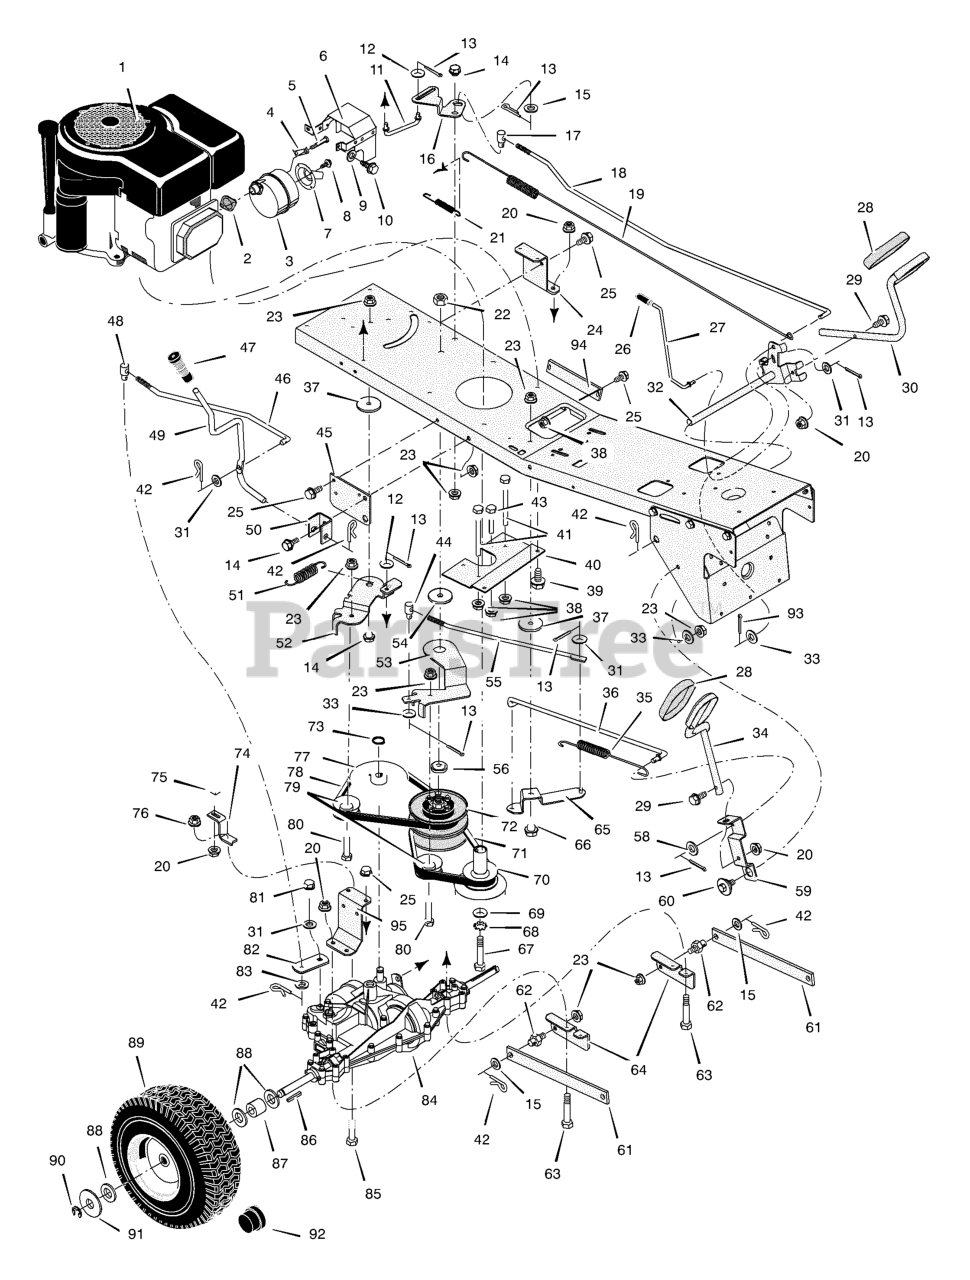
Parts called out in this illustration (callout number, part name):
1	Engine
2	GASKET, Exhaust
3	Muffler
4	Lock, Muffler Screw
5	Bolt, Hex
6	Shield, Heat
7	Tube, Exhaust
9	Washer, Lock
10	Screw
11	Rod, Link
13	Pin, Cotter
14	Bolt, Shoulder
15	Washer
16	Link, Clutch
17	NUT, Adjusting, 1/2-13
18	Rod, Clutch Variator
19	Spring, Brake
20	Nut
21	Spring, Brake Return
23	Nut
24	Bracket, Transaxle -Left
27	Rod, Parking Brake
28	Pad, Pedal
29	Bolt, Hex
30	Rod, Clutch/Brake
32	Rod, Clutch/Brake Pivot
33	Washer
34	Pedal, Variator
35	Spring, Return
36	Rod, Variator Connect
38	Nut
39	Screw
40	Plate, Belt Guide
41	Guide, Belt -Long
42	Pin, Hair
43	Guide, Belt -Short
44	Nut, Adjusting
45	Bracket, Lift Pivot
46	Rod, Shift Link
47	Grip
48	Nut, Adjusting
49	Lever, Shift
50	Bracket, Pivot
51	Spring - Variator Drive
52	Arm, Idler
53	Arm, Clutch Ider
55	Link, Drive
58	Washer
59	Arm, Pedal
60	Bolt, Shoulder
62	Pin, Threaded
63	Bolt, Hex
64	Bracket, Rear Hanger
65	Link Assembly, Pivot
66	Bolt, Shoulder
67	Bolt, Hex
68	Lockwasher
70	Pulley Stack
71	Belt, Primary Drive
72	Pulley Assembly, Variator
73	Ring, Snap
74	Bracket, Torque Reactor
75	Bolt, Carriage
76	Nut, Stoverlock
77	Pulley, Transaxle
78	Belt, Secondary Drive
79	Pulley, Idler
80	Bolt, Hex
81	Cap Screw
82	Yoke, Shift
84	Transaxle
85	Bolt, Hex
86	Key, Square
87	SPACER, Rear Wheel
89	Wheel & Tire Assembly
92	Hub Cap
93	Pin, Cotter
94	Plate, Reinforecement
95	Bracket, Transaxle -Right
